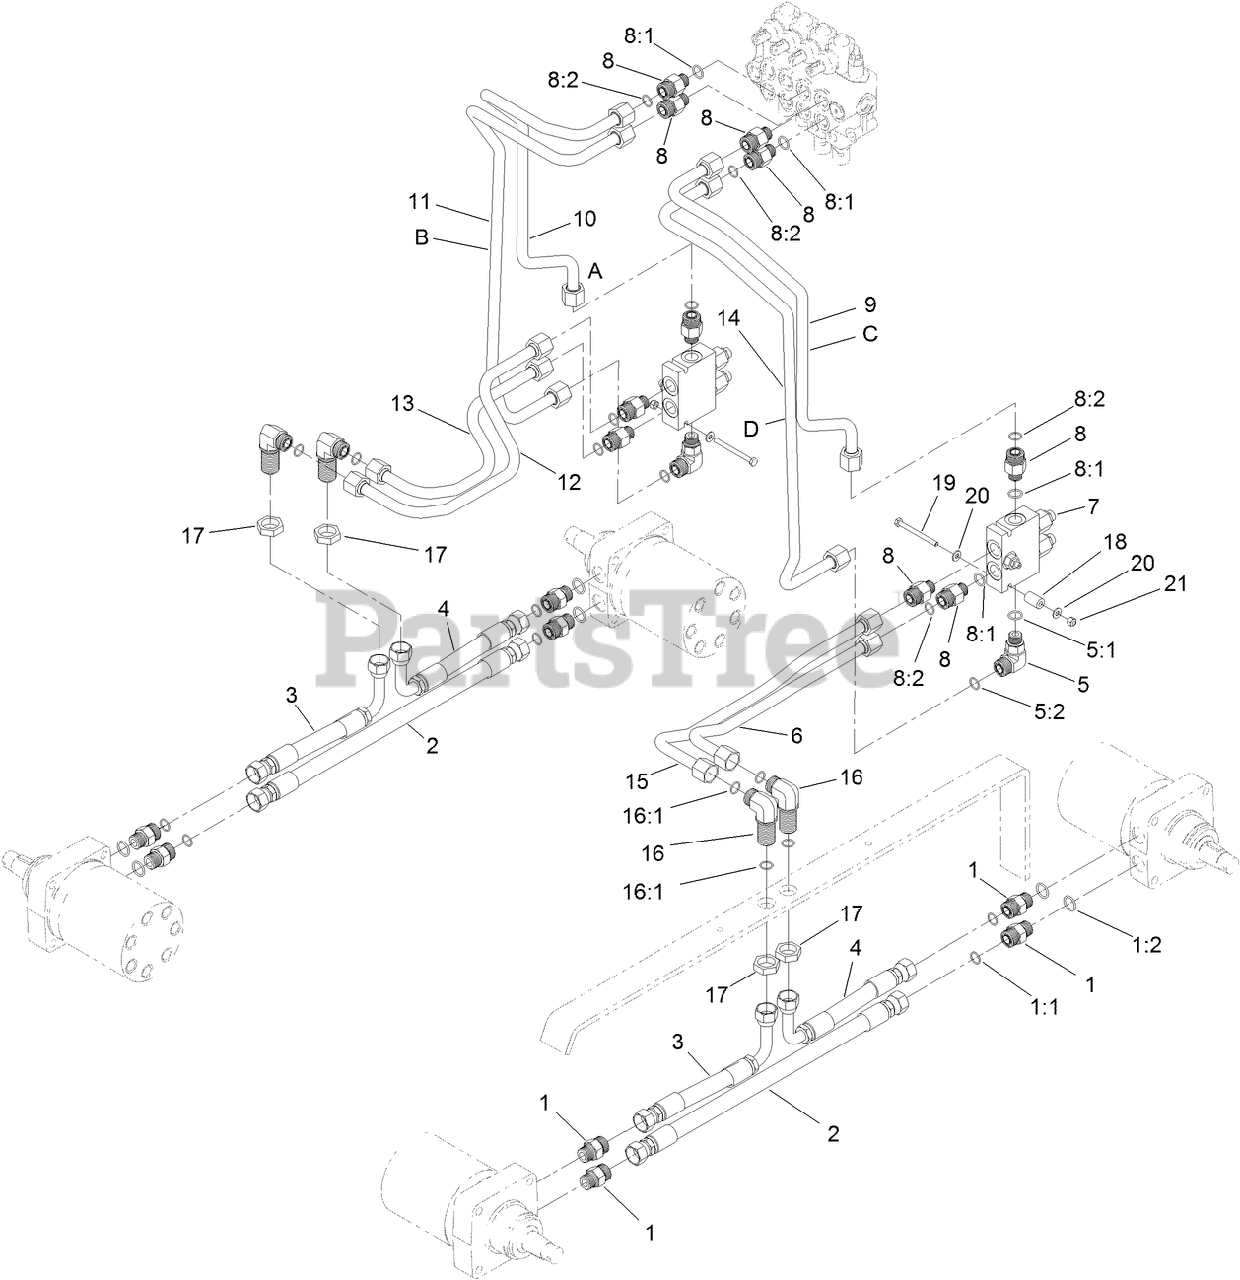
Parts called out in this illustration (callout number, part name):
1	FITTING-STRAIGHT
1:1	O-RING
1:2	O-RING
2	HYD HOSE ASM
3	HYD HOSE ASM
4	HYD HOSE ASM
5	Fitting-Elbow, 90 DEG
5:1	O-RING
5:2	O-RING
6	HYD TUBE ASM
7	HYD COUNTERBALANCE VALVE ASM
8	FITTING-STR
8:1	O-RING
8:2	O-RING
9	HYD TUBE ASM
10	HYD TUBE ASM
11	HYD TUBE ASM
12	HYD TUBE ASM
13	HYD TUBE ASM
14	HYD TUBE ASM
15	HYD TUBE ASM
16	FITTING-BULKHEAD, 90 DEG
16:1	O-RING
17	NUT-LOCK, BULKHEAD
18	SPACER-VALVE
19	SCREW-HH
20	WASHER-FLAT
21	NUT-LOCK, NI
